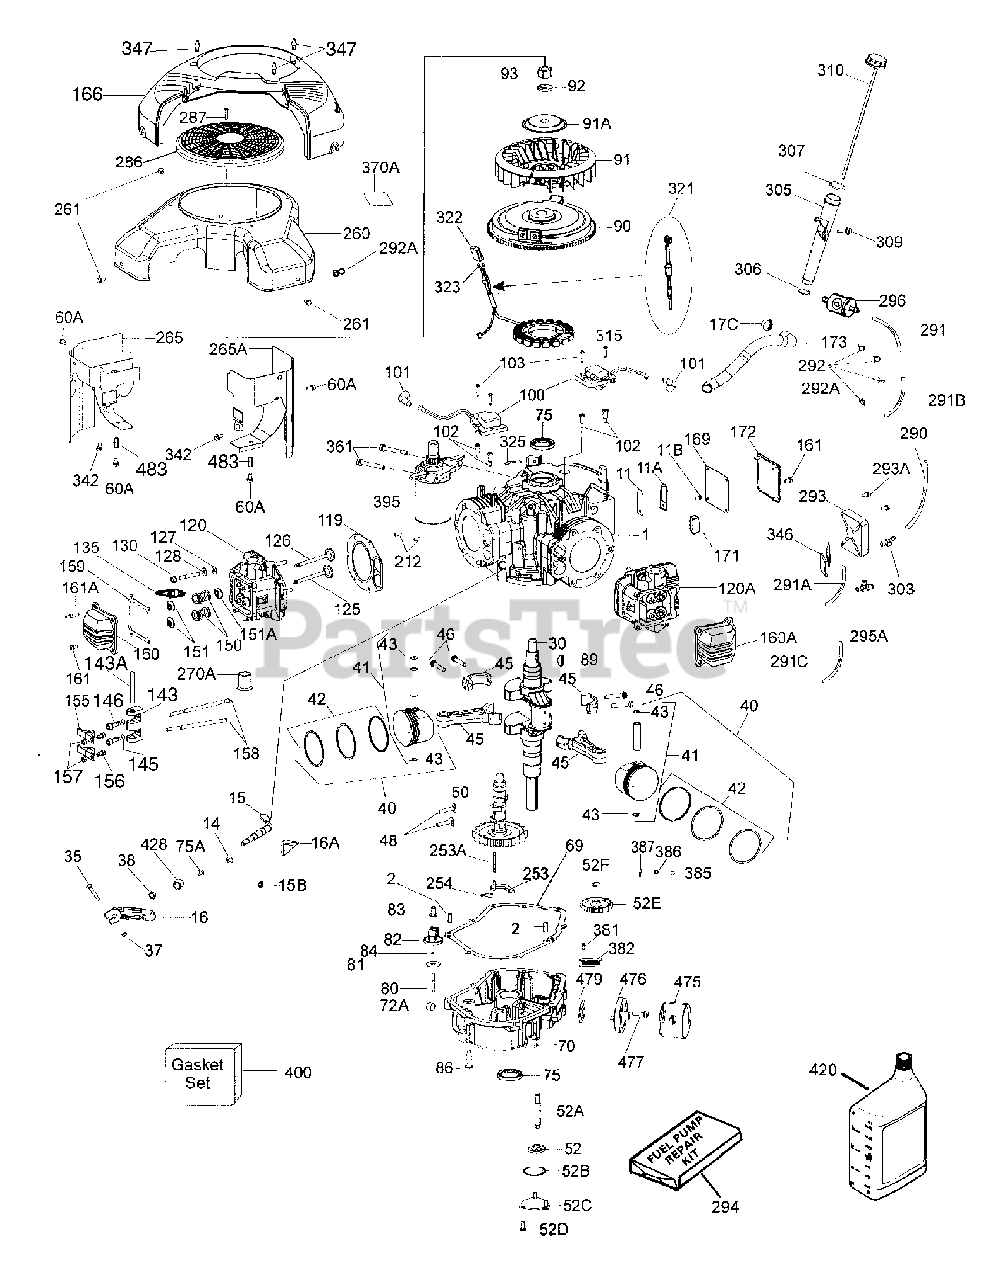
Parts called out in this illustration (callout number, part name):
11A	Breather Plate
11B	Screw, 10-32 x 7/16"
15	Governor Rod
15B	Screw, 1/4-20 x 5/8"
16	Governor Lever
16A	Governor Spring Bracket
17C	Breather Tube Clamp
35	Screw, Carriage 1/4-20 x 1-1/2"
37	Lock Nut, 1/4-20
38	Retaining Ring
40	Piston, Pin & Ring Set (Std.)
40	Piston, Pin & Ring Set (.010" OS)
41	Piston & Pin Ass'y. (Std.)
41	Piston & Pin Ass'y.(.010" OS)
42	Ring Set (Std.)
42	Ring Set (.010"OS)
43	Piston Pin Retaining Ring
45	Connecting Rod Ass'y.
46	Connecting Rod Bolt
48	Valve Lifter
50	Camshaft (MCR)
52	Oil Pump Ass'y.
52A	Oil Pump Shaft
52C	Oil Pump Cover
52D	Screw, T-30 1/4-20 x 43/64"
52E	Oil Pump Gear
52F	Oil Pump Gear Retaining Ring
60A	Screw, 1/4-20 x 1/2"
69	Mounting Flange Gasket
70	Mounting Flange
75	Oil Seal (1 in Ref 1, 1 in Ref 70)
75A	Oil Seal (Governor Shaft)
80	Governor Shaft
81	Washer (Governor Shaft)
82	Governor Gear Ass'y.
83	Governor Spool
84	Retaining Ring
86	Screw, 5/16-18 x 1-15/32"
90	Flywheel
91A	Flywheel Retainer
92	Belleville Washer
100	Solid State Ignition
101	Spark Plug Cover
102	Solid State Mounting Stud
103	Screw, T-15 10-24 x 15/16"
119	Cylinder Head Gasket
120	Cylinder Head, Opp. Breather Side
120A	Cylinder Head, Breather Side
125	Exhaust Valve (Std.)
126	Intake Valve (Std)
128	Belleville Washer
130	Screw, 5/16-18 x 2-1/2"(Head Mount)
135	Spark Plug (RN4C)
143	Rocker Arm Housing
143A	Rocker Arm Pin
146	Screw, T-45 5/16-24 X 29/32"
150	Valve Spring
151	Valve Keeper Retainer & Cap Set
151A	Valve Seal
156	Adjusting Screw
159	Rocker Arm Cover Gasket
160	Rocker Arm Cover, Opp. Breather Side
161	Screw, T-30 1/4-20 x 1/2"
161A	Stud, Valve Cover Mounting
166	Engine Shroud
169	Valve Cover Gasket
171	Breather Element
173	Breather Tube
253	Compression Release Weight
253A	Compression Release Pin
254	Compression Release Spring
260	Blower Housing (Black)
261	Shoulder Screw
265	Cylinder Head Cover, Opp. Breather
265A	Cylinder Head Cover, Breather Side
270A	Exhaust Port Liner
287	Screw, T-20 8-18 x 1-15/32"
290	Fuel Line (16.75")
291	Fuel Line (8-1/4")
291A	Fuel Line (8-1/4")
291C	Fuel Line (6.75")
292	Fuel Line Clamp
292A	Fuel Line Retainer
293	Pulse Pump
293A	Screw, 8-32 x 1-1/2"
295A	Fuel Fitting
296	Fuel Filter
303	Pulse Pump/Fuel Fitting
305	Oil Fill Tube
306	O-Ring (Oil Fill, Bottom)
307	O-Ring (Oil Fill, Top)
309	Screw, 1/4-20 x 57/64"
315	Alternator Coil (16 Amp)
322	Connector Body
342	Screw, 1/4-20 x 9/16"(Ref. 240 & 265)
346	Fuel Pump Bracket
347	Screw (without air duct)
347	Stud (with air duct)
361	Screw, 5/16-18 x 2-3/8"
370A	Lubrication Decal
381	Screw, 8-32 x 27/64"
382	Oil Strainer Screen
386	Pressure Release Spring
395	Electric Starter Motor (12 Volt)
400	Gasket Set
476	Oil Filter Adaptor
477	Screw, T-30 5/16-18 x 1 3/32"
479	Oil Filter Adaptor Gasket
